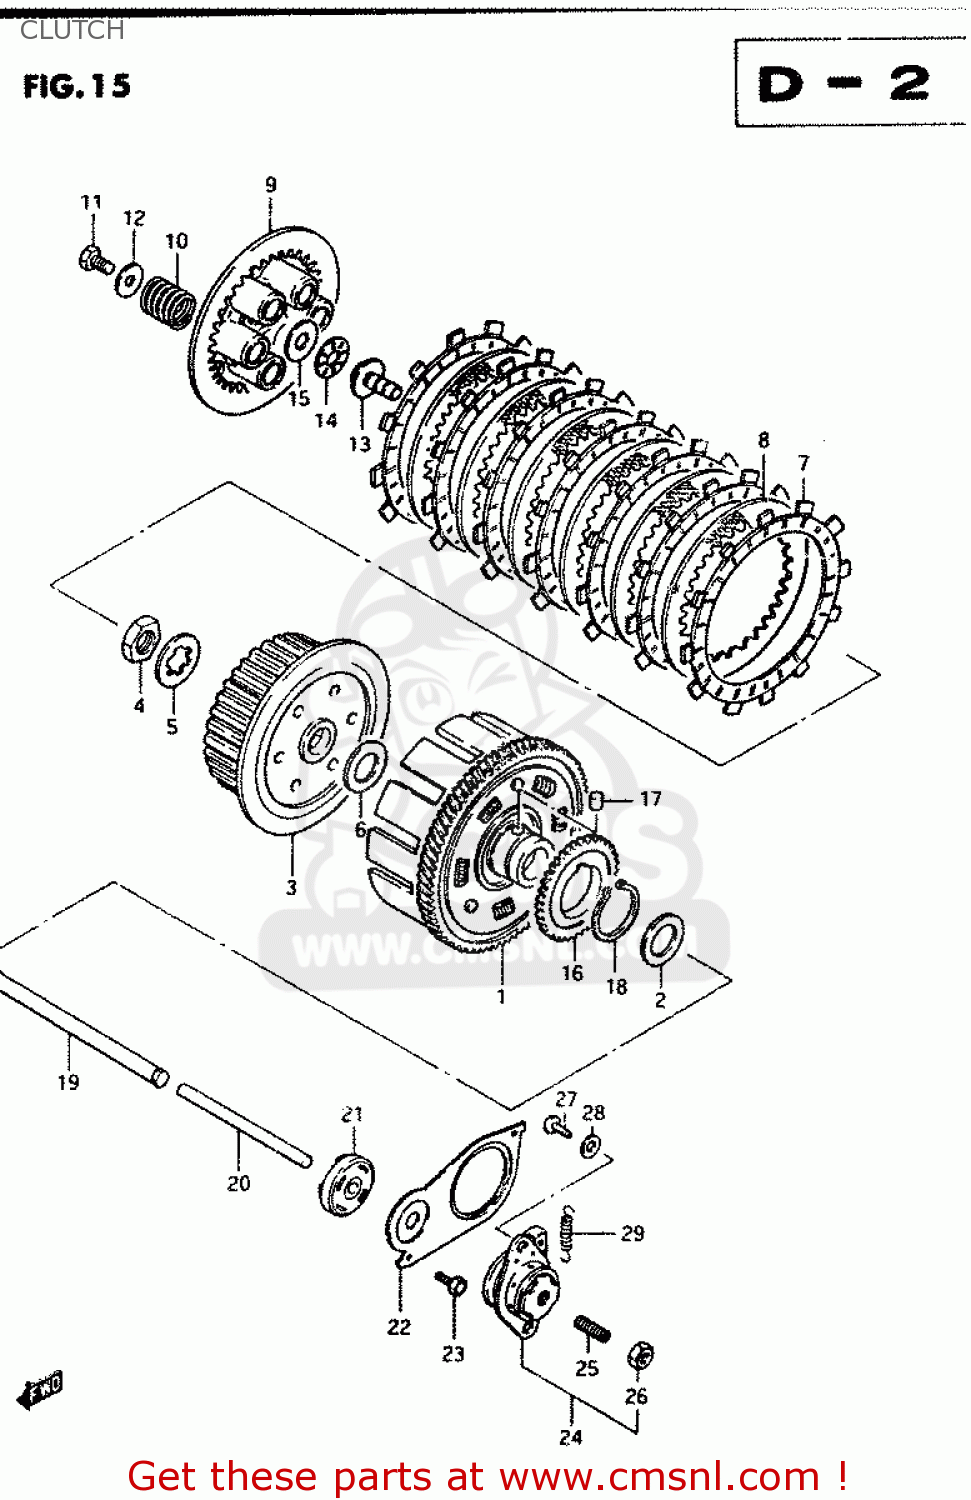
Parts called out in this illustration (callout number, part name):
1	GEAR ASSEMBLY,PRIMARY DRIVE
2	WASHER
3	HUB,CLUTCH SLEEVE
4	NUT (20MM)
5	WASHER,LOCK
6	WASHER(20X44X3)
7	PLATE,CLUTCH DRIVE (MCA)
8	PLATE,CLUTCH DRIVEN (NAS)
9	DISC,CLUTCH PRESSURE
10	SPRING
11	BOLT, UPPER
12	WASHER
13	PIECE,CLUTCH PUSH
14	BEARING(15X28X2)
15	WASHER
16	GEAR,OIL PUMP DRIVE
17	PIN(6X6)
18	CIRCLIP
19	ROD,CLUTCH PUSH
20	ROD,CLUTCH PUSH
21	SEAL,OIL(6X34X10)
22	PLATE,CLUTCH PUSH ROD
23	BOLT
24	SCREW ASSY,CLUTCH RELEASE
25	SCREW
26	NUT 6MM
27	SCREW
28	WASHER
29	SPRING
